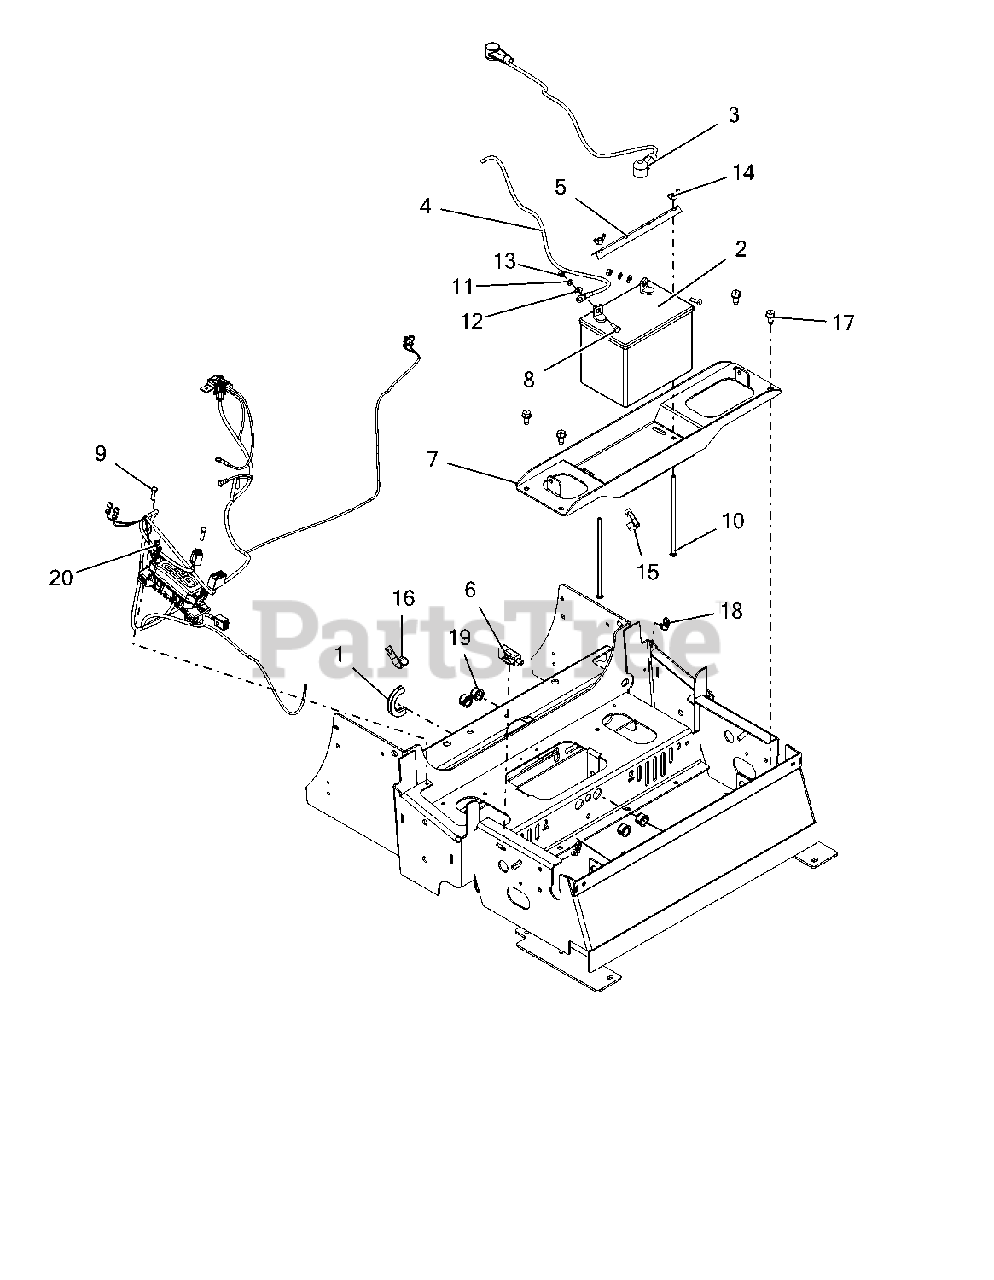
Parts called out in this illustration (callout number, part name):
1	STRIP, COWL
2	BATTERY, 300 CCA 10U1L
3	CABLE - POS BATT W/BOOTS 6X35
4	CABLE-NEGATIVE BATTERY 35.00"
5	HOLD DOWN
6	SWITCH, SNAP IN - N.O./N.O.
7	PT400 GAS BATTERY TRAY - RED
8	@BLT-HEX .25-20X.75 GR5 YWZC
9	@BLT-HEX M6-1.0X25 YWZC
10	BLT-RDHDSQNK .25-20X7.50 GR2YZ
11	@WSHR-LK .25X.062 REG YWZC
12	@WSHR-FL-STL.281X.62X.065 YWZC
13	@NUT-HEX .25-20 YWZC
14	NUT-LK WING .250-20 YWZC
17	@SCR-TAP .38-16X.75 HWH TR YWZ
18	CABLE TIE W/ TREE (.25 HOLE)
19	BUSH, PANEL SNAP .687X.875X.56
20	HARNESS, PT400 WIRING
